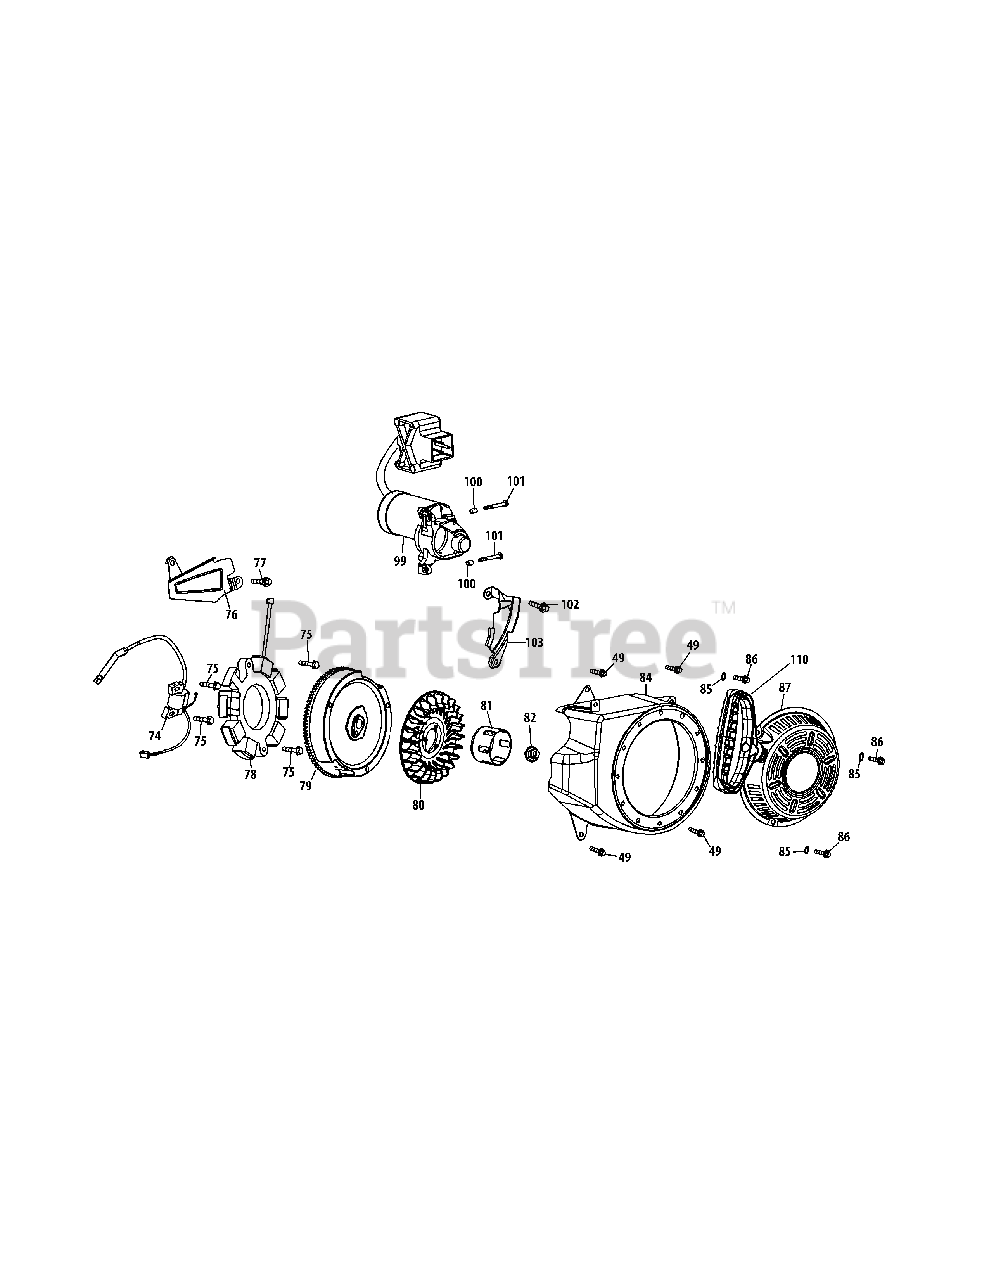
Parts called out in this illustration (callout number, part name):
49	Bolt M6×12
74	Ignition Coil Assembly
75	Bolt M6×25
76	Air Flow Shield
77	Bolt M6×10
78	Coil Assy., Charge
80	Cooling Fan
81	Starter Cup
82	Nut, Special, M14×1.5
84	Blower Housing
85	Washer
86	Bolt M6×10
87	Recoil Starter
99	Electric Starter
100	Dowel Pin 8×8
101	Bolt M6×32
102	Bolt M6×18
103	Blower Housing Shield
110	Starter Handle
